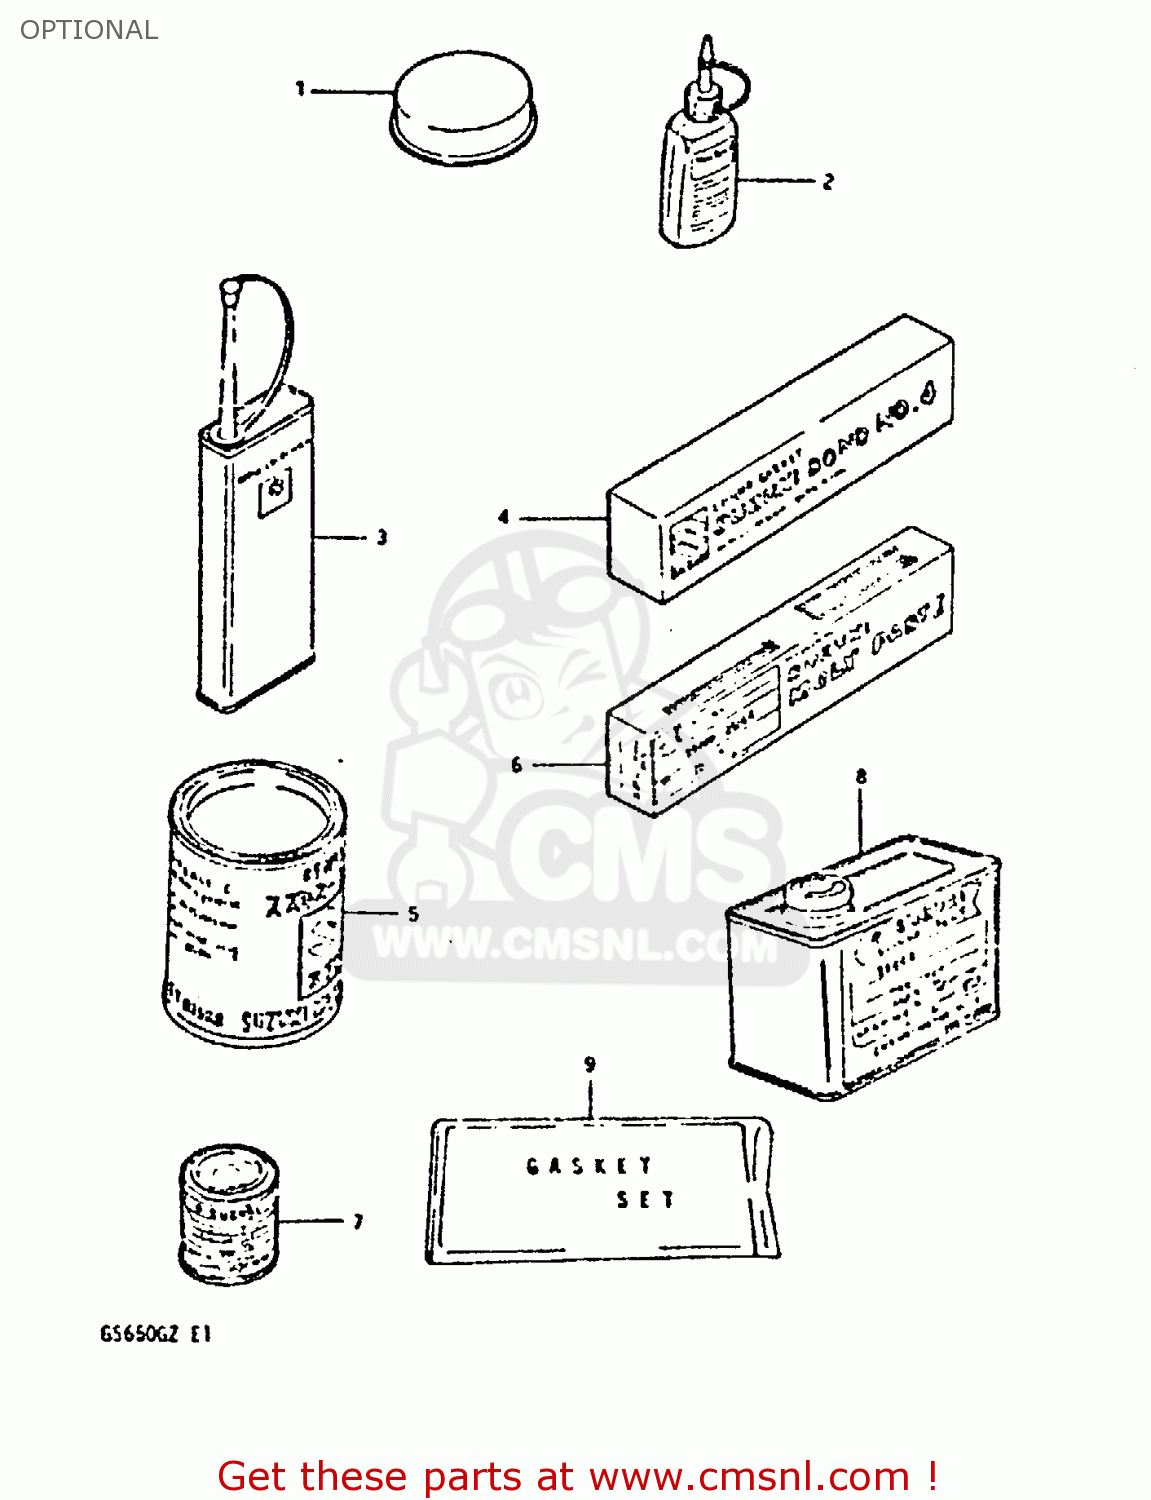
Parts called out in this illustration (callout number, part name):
1	GREASE,PBC FOR BRK PAD 20G
2	THREAD LOCK SUPER (1332B)
3	THREAD LOCK NO.1401 CLEAR 200G
4	BOND 1104
5	GREASE(C)EP2 LITHIUM 150G
6	SUZUKI MOLY PASTE
7	PAINT BLIGHT S
8	PAINT (ROCKY WHITE)
9	GASKET SET
